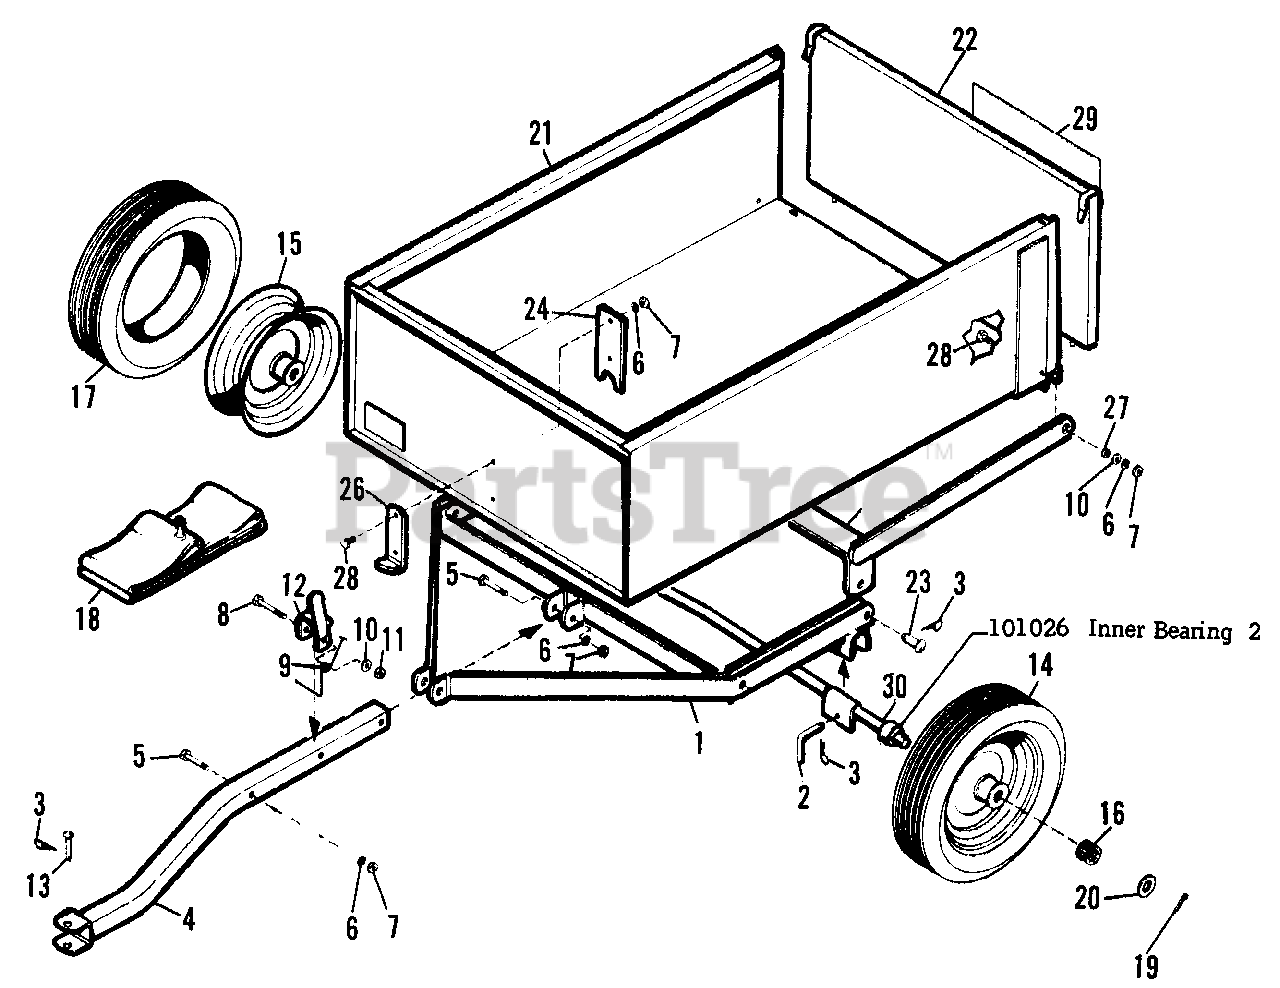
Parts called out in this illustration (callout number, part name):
1	Frame Assembly
3	Spring Clip
4	Tongue Assembly
5	Hex Capscrew 3/8"-16 x 2-1/4" lg.
6	Lock Washer 3/8"
7	Hex Nut, Full 3/8"-16
8	Hex Capscrew, 3/8"-16 x 2-3/4" lg.
9	Torsion Spring
10	Plain Washer 3/8"
11	Hex Nut, Full 3/8"-16
12	Box Catch Clevis Assembly
14	Wheel & Tire Assembly
19	Cotter Pin 3/16"-1-1/2" lg.
20	Plain Washer 3/4"
21	Trailer Body
24	Box Guide Plate
25	Box Pivot Assembly
26	Box Catch Plate
28	Hex Capscrew 3/8"-16 x 1" lg.
30	Axle Assembly
